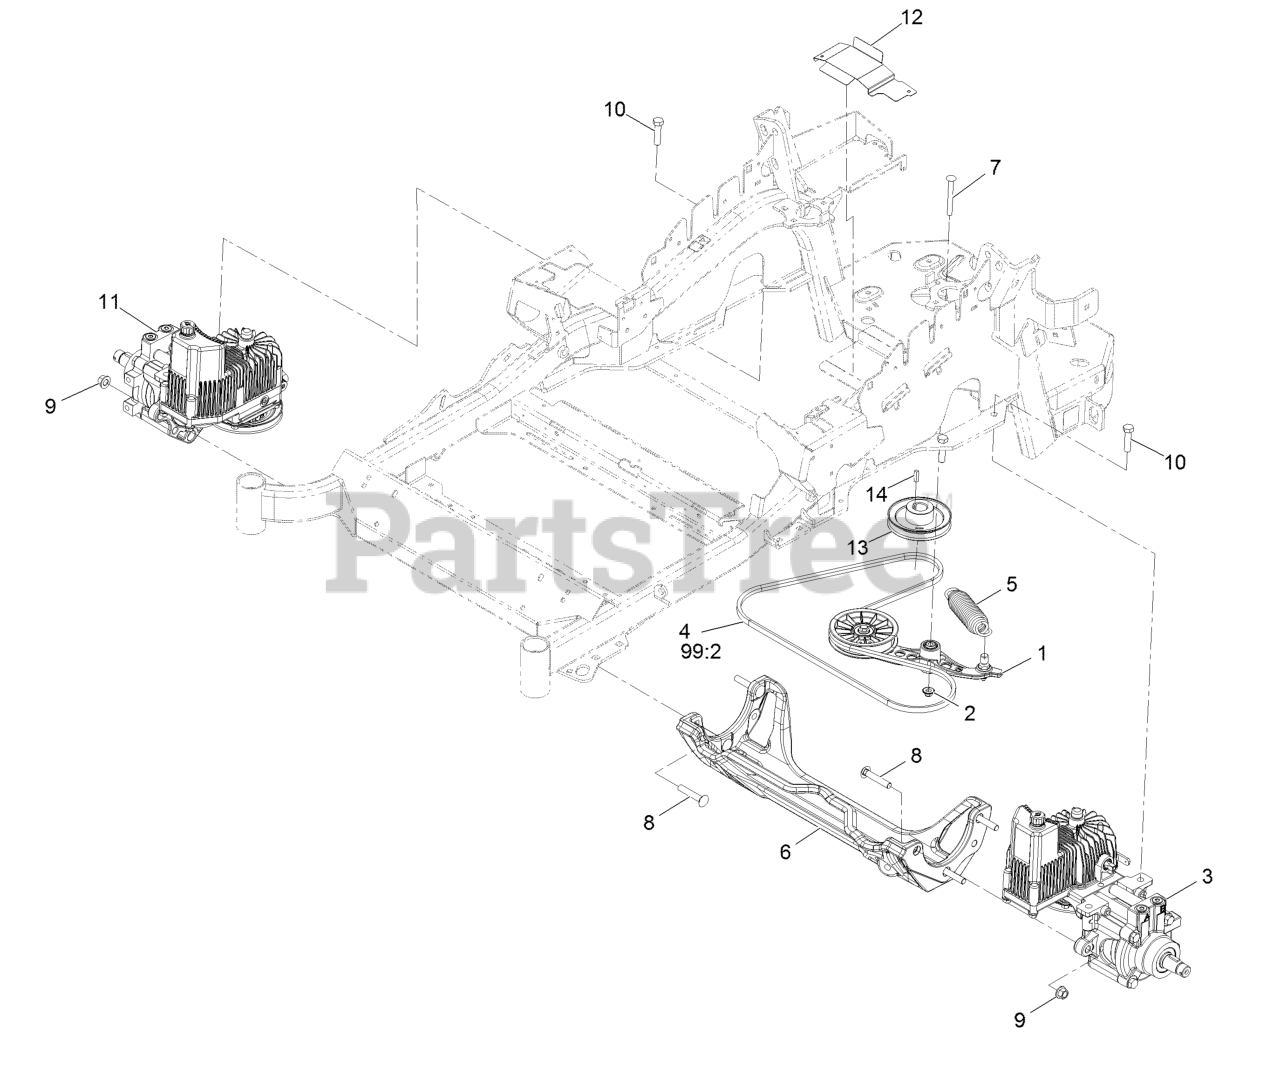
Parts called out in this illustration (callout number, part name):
1	Pump Idler ASM
2	Nut-Nyloc 3/8-16 Flg
3	LH Hydro ASM (12Cc No Fan)
4	Belt-V
5	Spring-Extension
6	Cradle-Hydro
7	Bolt-Carriage Shoulder 3/8-16 X 3 1/2
8	Screw-CARR
9	Nut-Lock 1/2-13
10	Screw-HH 1/2-13 X 1 1/4
11	RH Hydro ASM (12Cc No Fan)
12	Guard-Belt
13	Sheave-Pump, Drive
14	Key-Machine 1/4 X 1/4 X 1
99	Bottle-Oil, 32Oz Hydraulic
99	Filter-Hydro
99	Bottle,Oil 1 Gallon Hydraulic
99	Kit,Hydro Service
99:1	Bottle-Oil, 32Oz Hydraulic
99:2	Belt-V
99:3	Filter-Hydro
